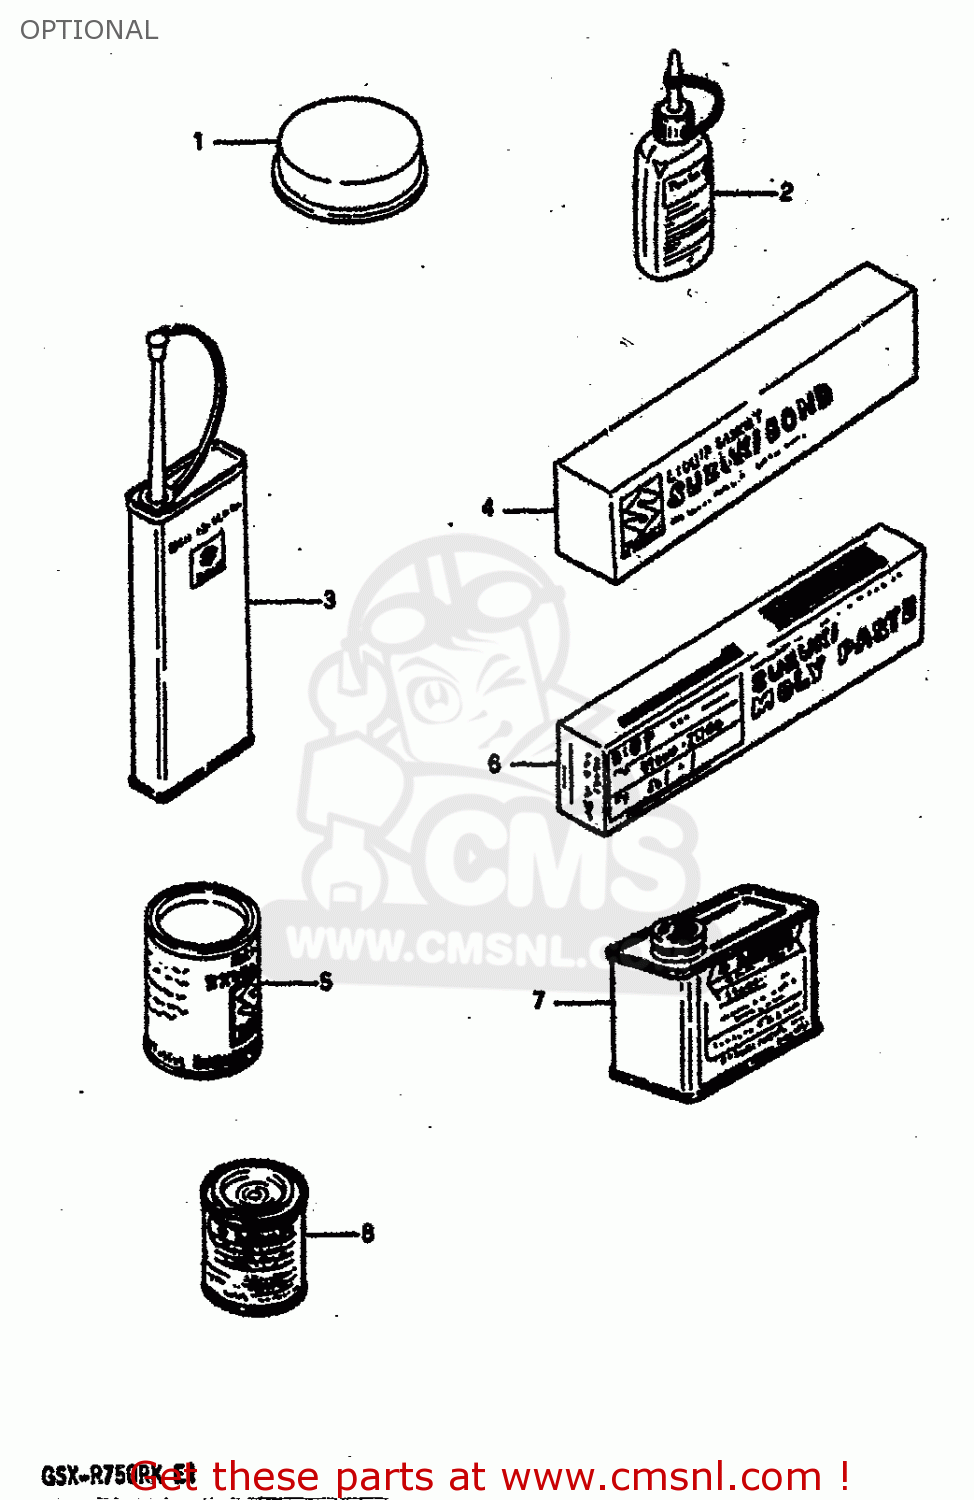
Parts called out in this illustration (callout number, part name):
1	GREASE,PBC FOR BRK PAD 20G
2	THREAD LOCK NO.1342
3	THREAD LOCK NO.1401 CLEAR 200G
4	LIQUID GSKT NO.1207B 100G BLK
5	GREASE(C)EP2 LITHIUM 150G
6	SUZUKI MOLY PASTE
7	PAINT (SPECIAL WHITE)
8	PAINT (SPECIAL WHITE)
